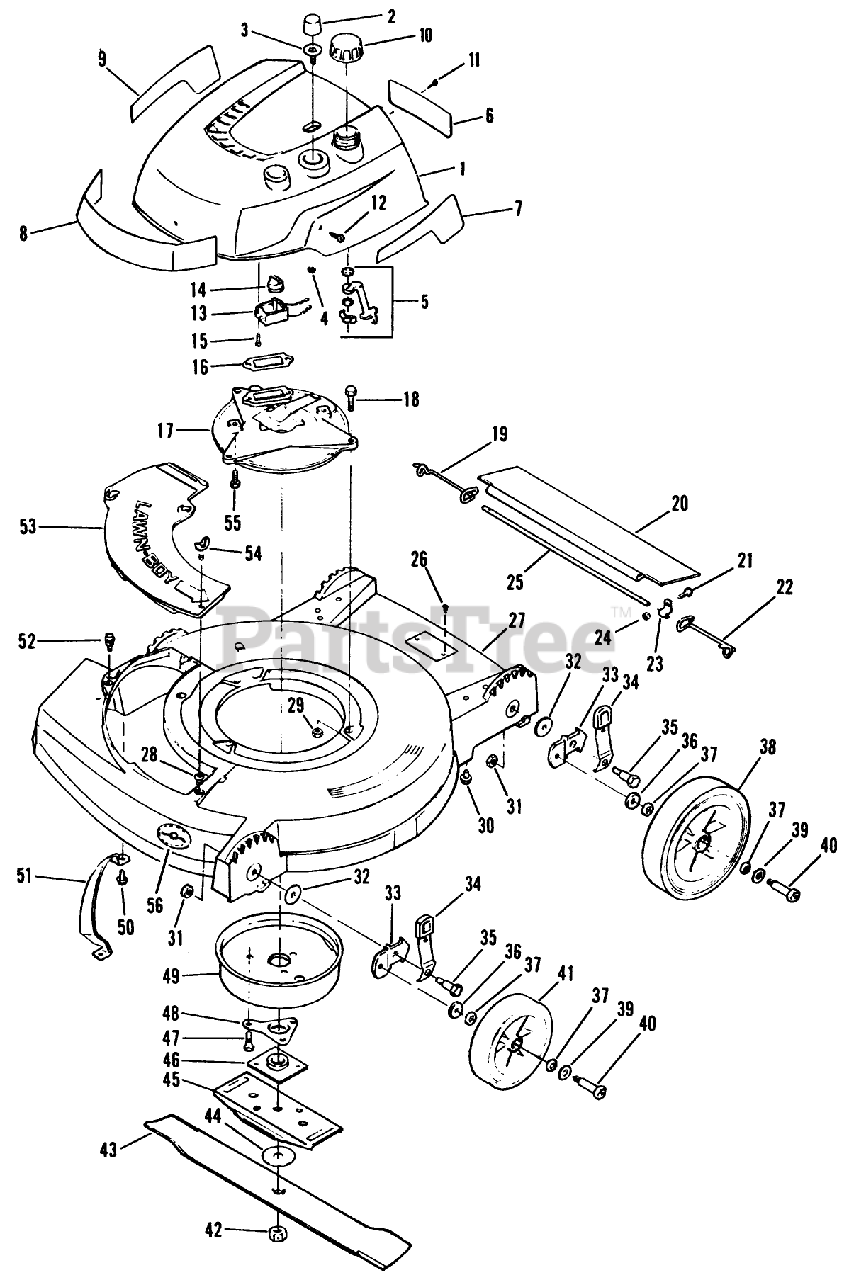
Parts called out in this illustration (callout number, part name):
4	LOCKNUT S
6	Decal-Instruction
9	DECAL
11	SCREW S
12	SCREW-SEMS
14	SWITCH KNOB
19	SPRING;TRAILING SHIELD RH
20	TRAILING SHIELD-19
20	SHIELD
22	SPRIG T/SHLD ASOC
23	CLAMP ROD KMC
24	LOCKNUT E
25	ROD T/SHIELD ADV WIRE
25	ROD 21" ADVANCE
29	NUT-LOCK F
31	LOCKNUT
36	WASHER WROUGHT
40	BOLT WHEEL
42	NUT-BLADE
44	WASHER
46	PLATE AND COLLAR ASM
48	SUPPORT F
51	TOE BAR 19"
51	BAR-TOE
53	COVER PLATE
54	WING SCREW LAWRE
55	SCREW V
